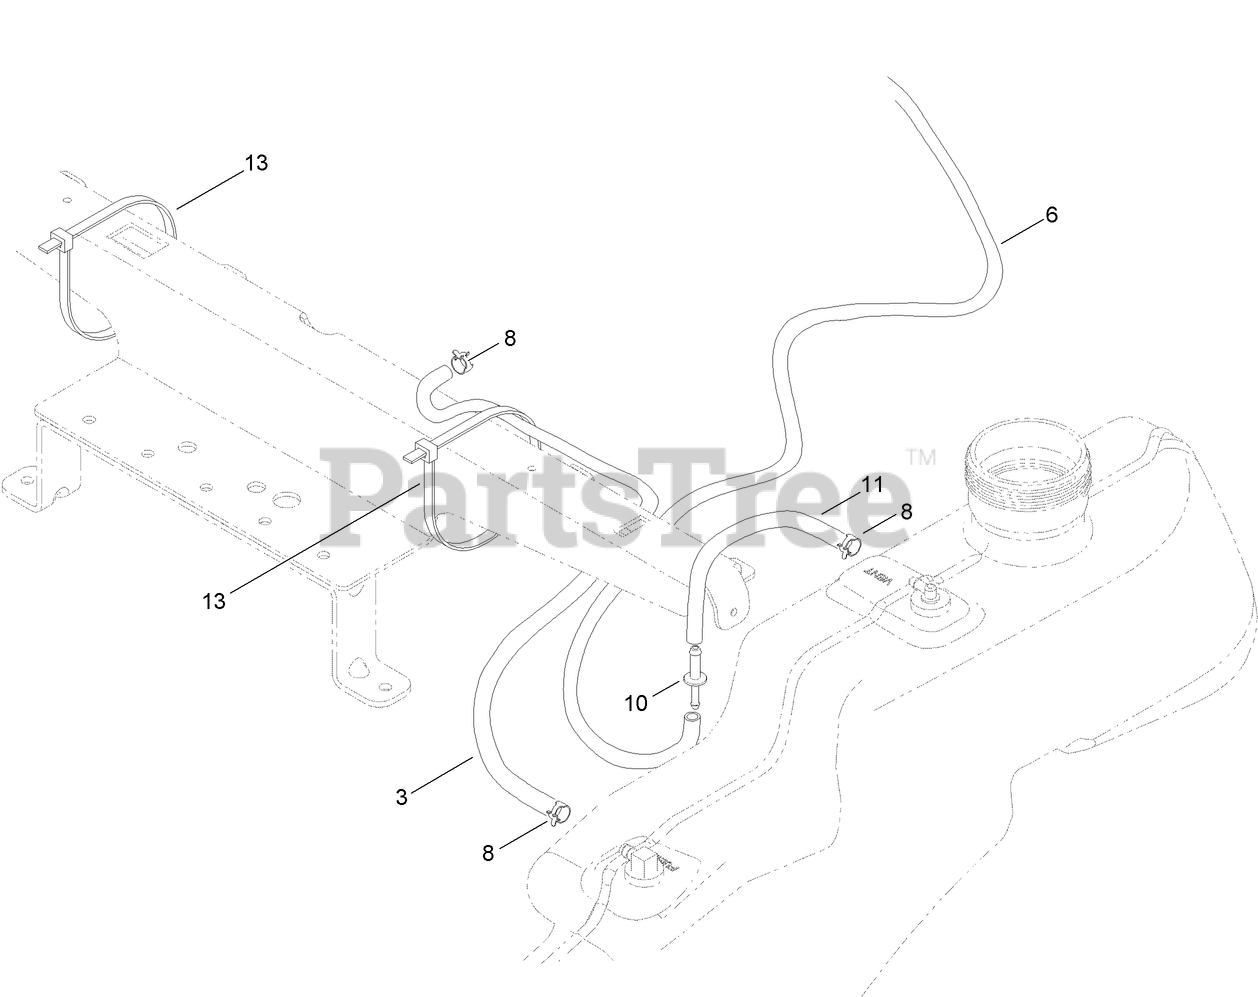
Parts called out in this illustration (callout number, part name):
3	HOSE-FUEL
6	HOSE-FUEL
8	CLAMP-HOSE
10	ADAPTOR-ORIFICE
11	HOSE-FUEL
13	TIE-CABLE
